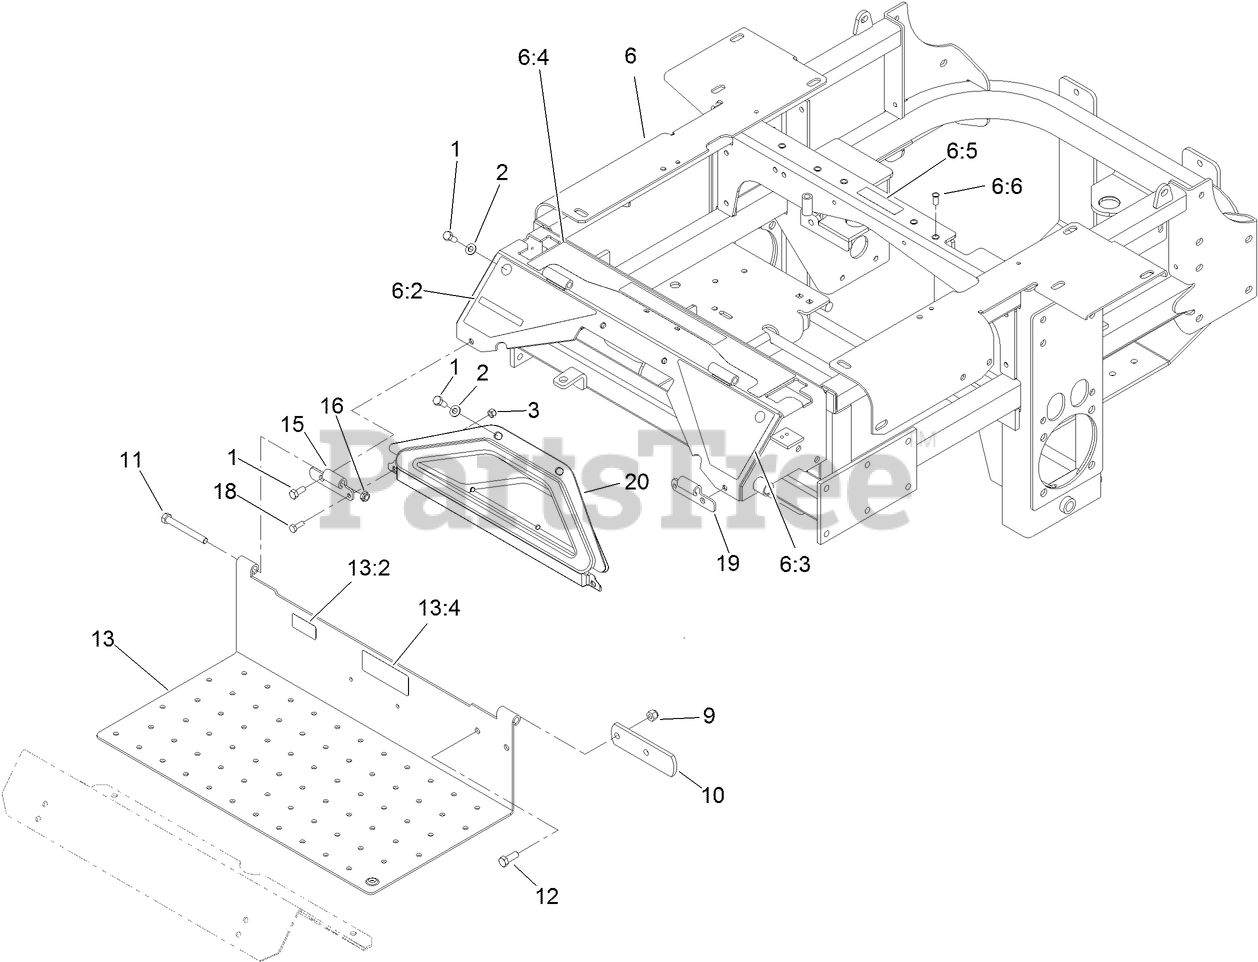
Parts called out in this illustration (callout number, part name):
1	SCREW-HH
2	WASHER-FLAT
3	NUT-LOCK, NI
6	TRACTION FRAME ASM
6:2	DECAL-WARNING
6:3	DECAL-DANGER
6:4	DECAL-CONSOLE, TOP
6:5	DECAL-COVER, MISSING
6:6	NUT-CLINCH
9	NUT-LOCK, NI
10	STOP-BRAKE, PARK
11	SCREW-HH
12	SCREW-HH
13	FLOOR PAN ASM
13:2	DECAL-PROTECTION, EAR
13:4	DECAL-DIESEL, BIO-READY
15	HINGE-FLOORPAN, LH
18	SCREW-HH
19	HINGE-FLOORPAN, RH
20	POCKET
